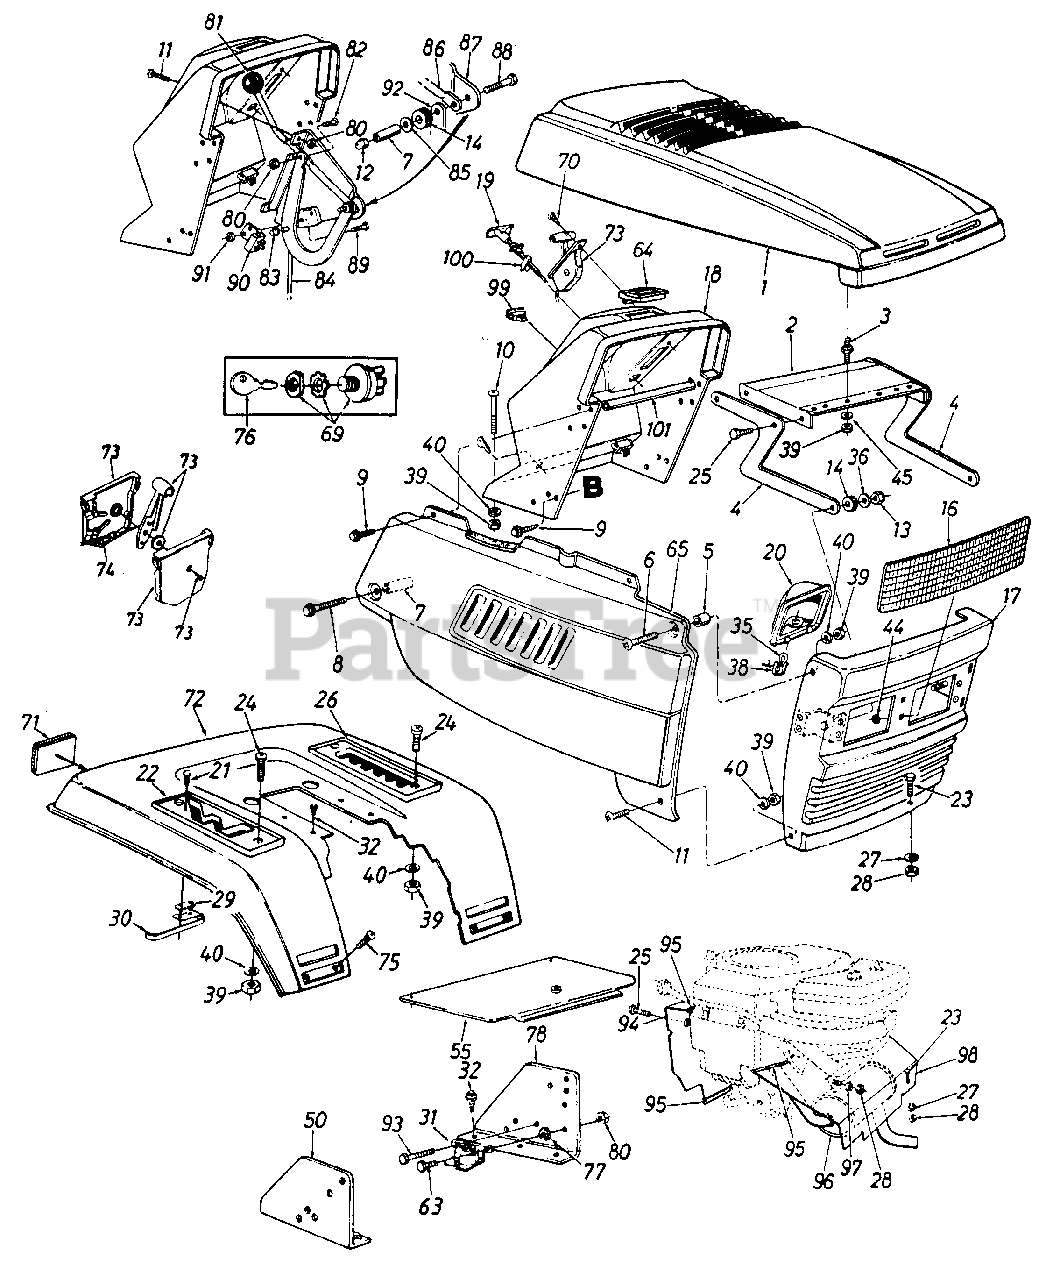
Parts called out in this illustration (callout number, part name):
2	Hood Plate
3	Double Ended Stud 1/4-20 Thd.
4	Hood Hinge
5	Spacer .34" I.D. x .437"
6	Truss Hd. Mach. Scr. 1/4-20 Thd.
7	Spacer .26" I.D. x .375"
8	Hex Wash. TT-Tap Scr. 1/4-20 x 1.75" Lg.
9	Hex T-Tap Scr. 1/4-20 x .75" Lg.
10	Truss Mach. Scr. 1/4-20 x 1.75" Lg.
11	Truss Mach. Scr. 1/4-20 x .5" Lg.
12	Hex Ins. L-Nut 1/4-20 Thd.
13	Hex L-Nut 5/16-18 Thd.
14	Rubber Washer
16	Headlight Lens
19	Choke Control
20	Headlight Housing
21	Hex Wash. Hd. AB-Tap Scr. #8 x .5" Lg.
22	Forward/Reverse Index Brkt.
23	Hex Bolt 5/16-18 x .75" Lg.
24	Truss Mach. Scr. 1/4-20 x .75" Lg.
25	Hex Wash. Hd. Scr. 1/4" x .5" Lg.
26	7-5peed Index Brkt.
27	L-Wash. 5/16" I.D.
28	Hex Nut 5/16-18 Thd.
29	Insulator Nut Plate
30	Reverse Safety Switch
31	Solenoid
32	Hex Hd. Rolling Scr. 5/16-24 x .75" Lg.
35	Lamp
36	Bell-Wash. .34" I.D. x .87"
38	Socket
39	Hex Nut 1/4-20 Thd.
40	L-Wash. 1/4" I.D.
44	Speed Nut 5/16" I.D.
45	Bell-Wash. .265" I.D. x .75" O.D.
50	Dash Support Brkt.-R.H.
55	Transmission Cover Ass'y.
63	Hex Bolt 1/4-20 x .5" Lg.
64	Ammeter
70	Truss Mach. AB-Tap Scr. #10 x .5" Lg.
71	Reflector
74	Throttle Control Wire 35" Lg.
75	Carriage Bolt 1/4-20 x .5" Lg.
76	Key
77	Ext. L-Wash. 1/4" I.D.
78	Dash Support Brkt.-L.H.
80	Hex Sems Nut 1/4-20 Thd.
81	Ball Knob
82	Hex Bolt 1/4-20 x .62" Lg.
83	Push Nut
84	PTO Rod
85	Fl-Wash. .281" I.D. x .73"
86	PTO Lever
87	Deck Clutch Control Brkt.
88	Hex Bolt 1/4-20 x 2.5" Lg.
89	Truss Mach. Scr. #10-24 x .5" Lg.
90	Safety Switch
91	Hex Nut #10-24 Thd.
92	PTO Bracket
93	Self Clinching Stud 1/4-20 x .5" Lg.
94	Engine Baffle
95	Trim Strip 10" Lg.
96	Muffler
97	Spec. L-Wash. 5/16" I.D.
98	Front Heat Shield
99	Light Switch
100	Retainer Clip
101	Dash Support Tube
